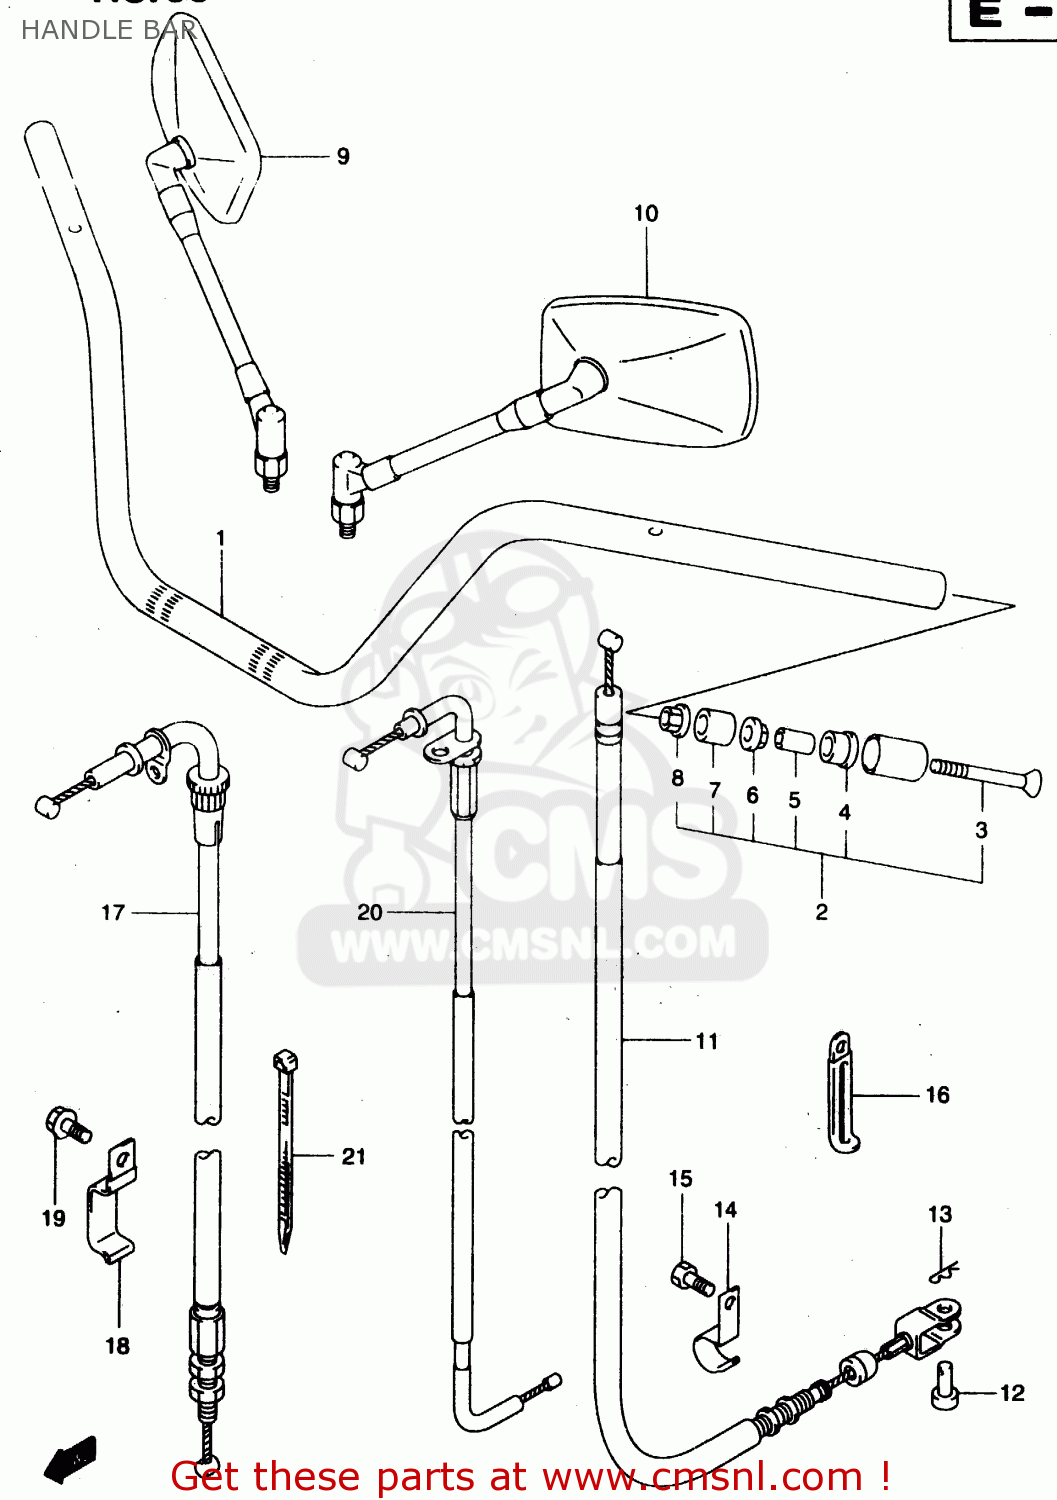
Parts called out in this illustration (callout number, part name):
1	HANDLEBAR
2	BALANCER SET,HANDLEBAR
3	SCREW(6X125)
4	EXPANDER,HANDLE BALANCER NO.2
5	SPACER,EXPANDER
6	WASHER(6.5X14X2.3)
7	EXPANDER,HANDLE BALANCER
8	NUT
9	MIRROR ASSEMBLY,REAR VIEW
10	MIRROR ASSEMBLY,REAR VIEW
11	CABLE ASSY,CLUTCH
12	PIN(L:13)
13	PIN
14	CLAMP,CLUTCH CABLE NO.1
15	SCREW
16	CLAMP(L:65 T:0.8)
17	CABLE ASSY,THROTTLE
18	CLAMP
19	BOLT
20	CABLE,STARTER
21	CLAMP(L:125)
